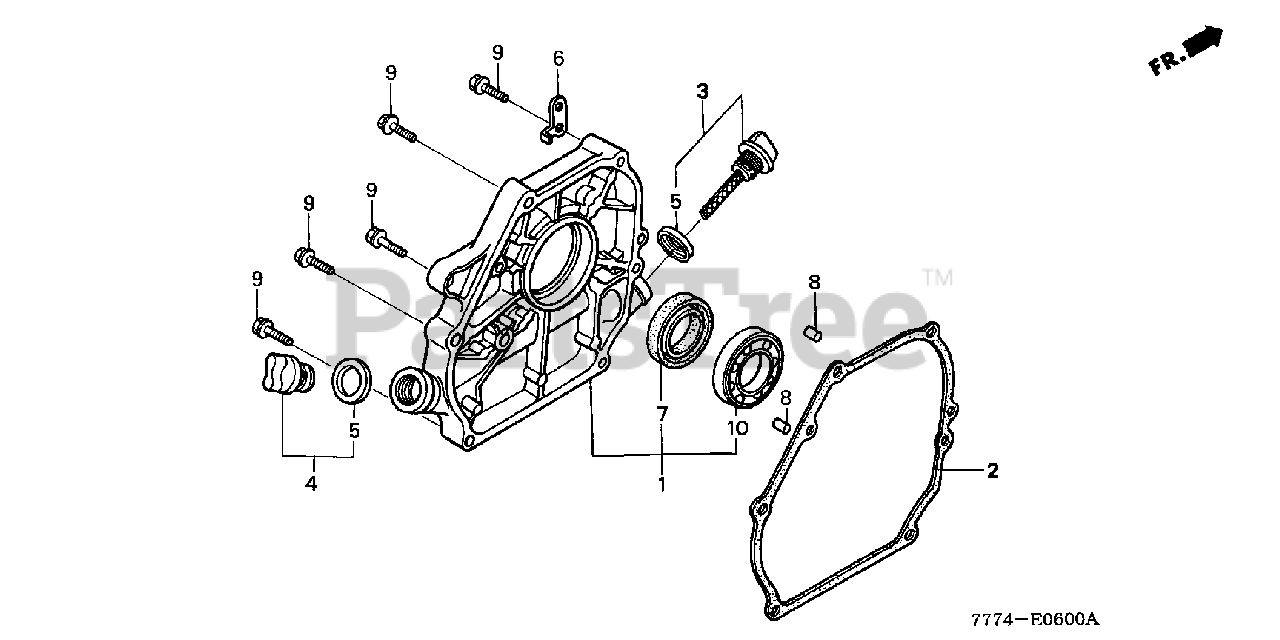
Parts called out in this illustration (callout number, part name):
1	COVER ASSY., CRANKCASE (S-TYPE)
1	COVER ASSY., CRANKCASE
2	GASKET, CASE COVER
3	CAP ASSY., OIL FILLER
4	CAP ASSY., OIL FILLER
5	GASKET, OIL FILLER CAP
6	STAY, WIRE CLIP (A)
7	OIL SEAL (25X41X6)
8	PIN, DOWEL (8X14)
9	BOLT, FLANGE (8X32)
10	BEARING, RADIAL BALL (6205)
